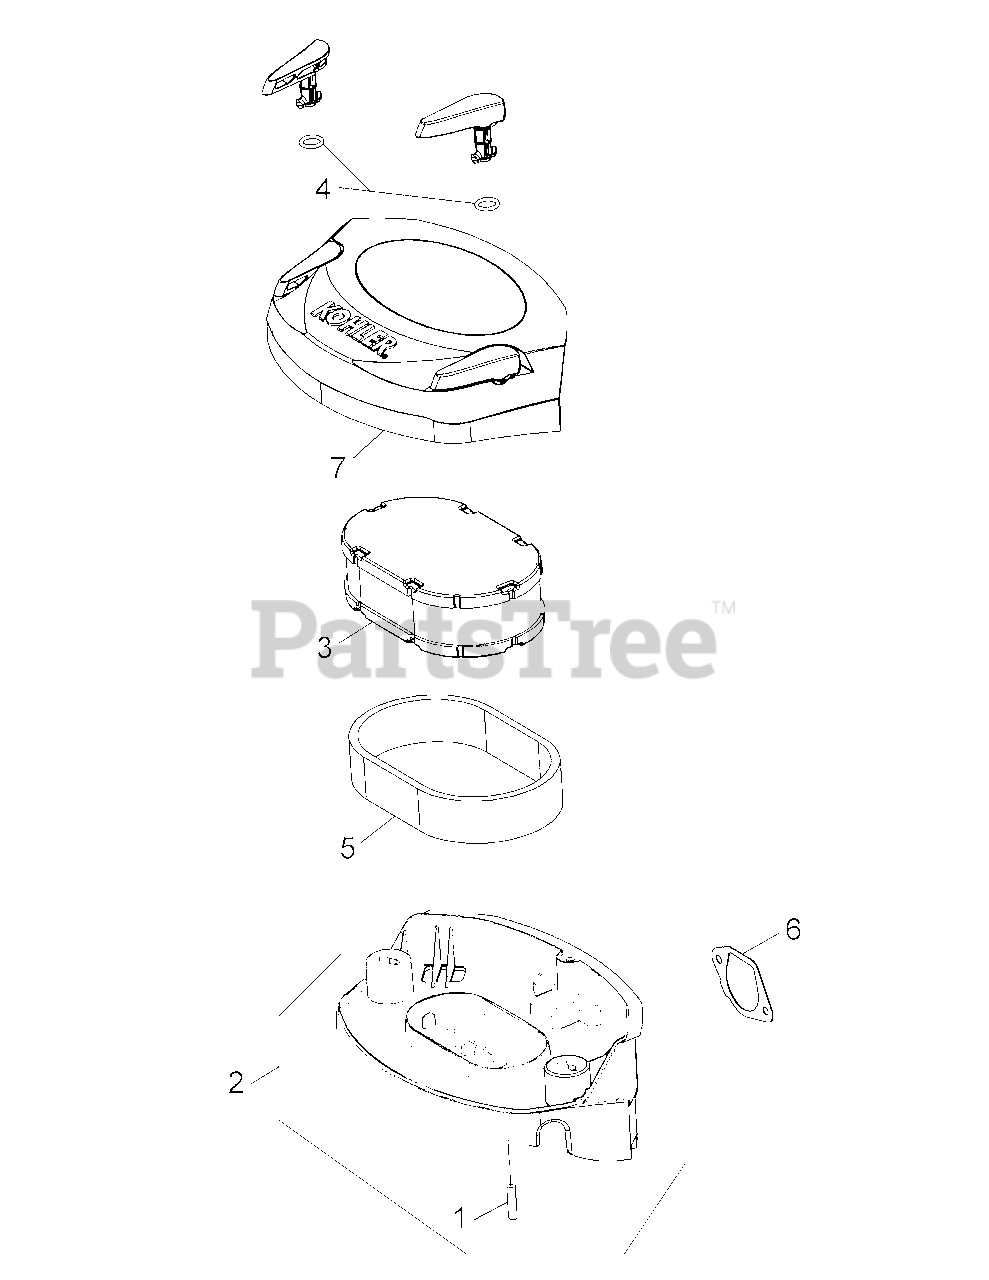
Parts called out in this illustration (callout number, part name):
2	Air Cleaner Base Assembly
3	Air Filter Element
5	Pre-Cleaner Element
6	Air Cleaner Base Gasket
7	Air Cleaner Cover Assembly
